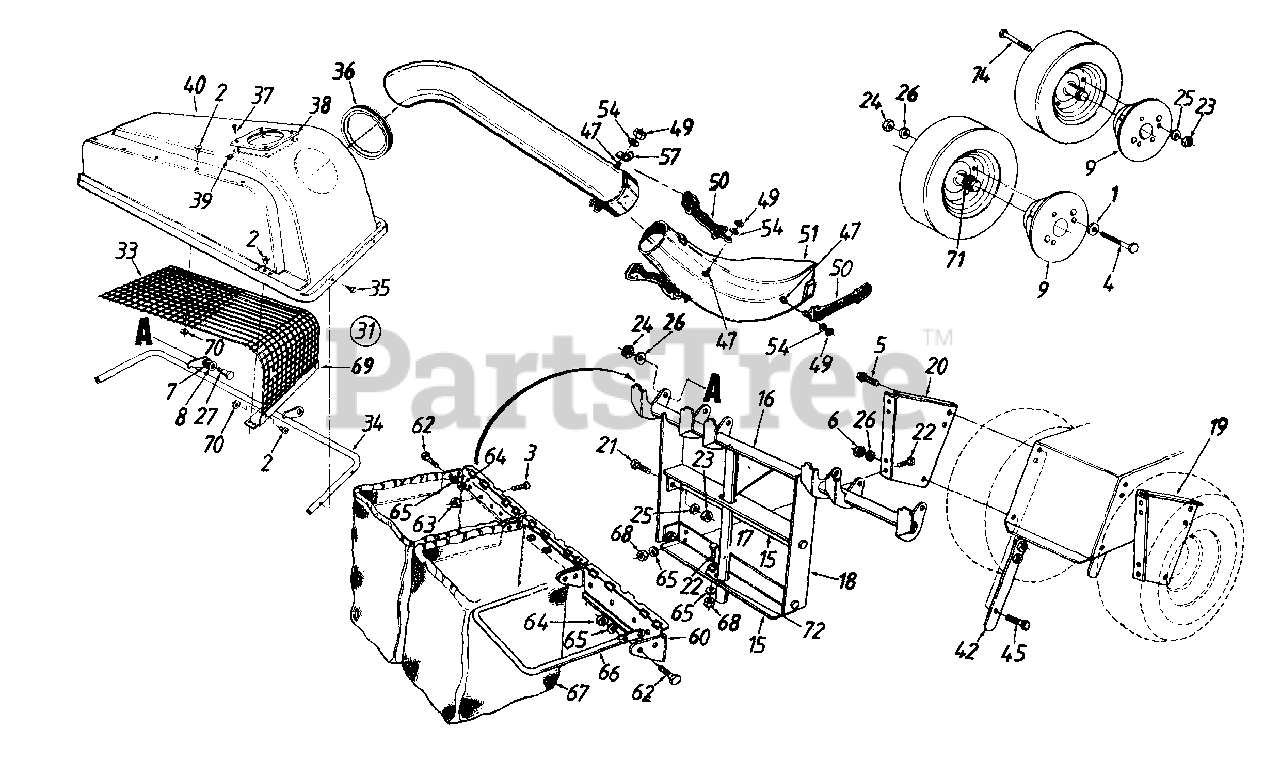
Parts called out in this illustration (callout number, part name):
1	Fl-Wash. .385" I.D.
2	Pop Rivet
3	Truss Mach. Scr. #10-24 x .38"
4	Hex Bolt 3/8-16 x 4.5" Lg.
5	Hex Wash. Hd. Tap Scr. 5/16-18 x .62"
6	Hex Nut 3/8-24 Thd.
7	Bell-Wash. .515" I.D.
8	Fl-Wash. .510" I.D.
17	Bell-Wash. .265" I.D.
18	Catcher Latch and Support Brkt.
21	Hex Bolt 5/16-18 x .75" Lg.
22	Hex Bolt 1/4-20 x .62" Lg. - Grade 5
23	Hex Nut 5/16-18 Thd.
24	Hex Nut 3/8-16 Thd.
25	L-Wash. 5/16" I.D.
26	L-Wash. 3/8" I.D.
27	Shld. Bolt 3/8-16 x .500" Dia.
28	Bell-Wash. .505" I.D. x 1.0" O.D.
31	Grass Catcher Cover Ass'y. Comp.
33	Screen
34	Hinge Brkt. Ass'y.
35	Hex Tap Scr. 1/4-20 x .5" Lg.
36	Tube Seal
37	Truss Mach. B-Tap Scr. #10 x .5" Lg.
38	Plastic Plate
39	Speed Nut
40	Grass Catcher Cover
47	Hex Bolt 1/4-20 x .50" Lg.
49	Hex Ins. L-Nut 1/4-20 Thd.
50	Retainer Strap Ass'y.
51	Discharge Chute
53	Catcher Elbow Tube
54	L-Wash. .270" I.D. x .57" O.D.
57	Retainer Hook Brkt.
60	Bag Frame Hanger Brkt.
62	Hex Bolt 1/4-28 x .75" Lg.
63	Hex Sems Nut #10-24 Thd.
64	Hex Nut 1/4-28 Thd.
65	L-Wash. 1/4" I.D.
66	Catcher Bag Frame
67	Grass Catcher Bag
68	Hex Nut 1/4-20 Thd.
71	Foam Strip 1-1/8" x 1-1/2" x 3/8"
72	Support Tubing Adapter Brkt.
74	Hex Bolt 5/16-18 x 4" Lg.
